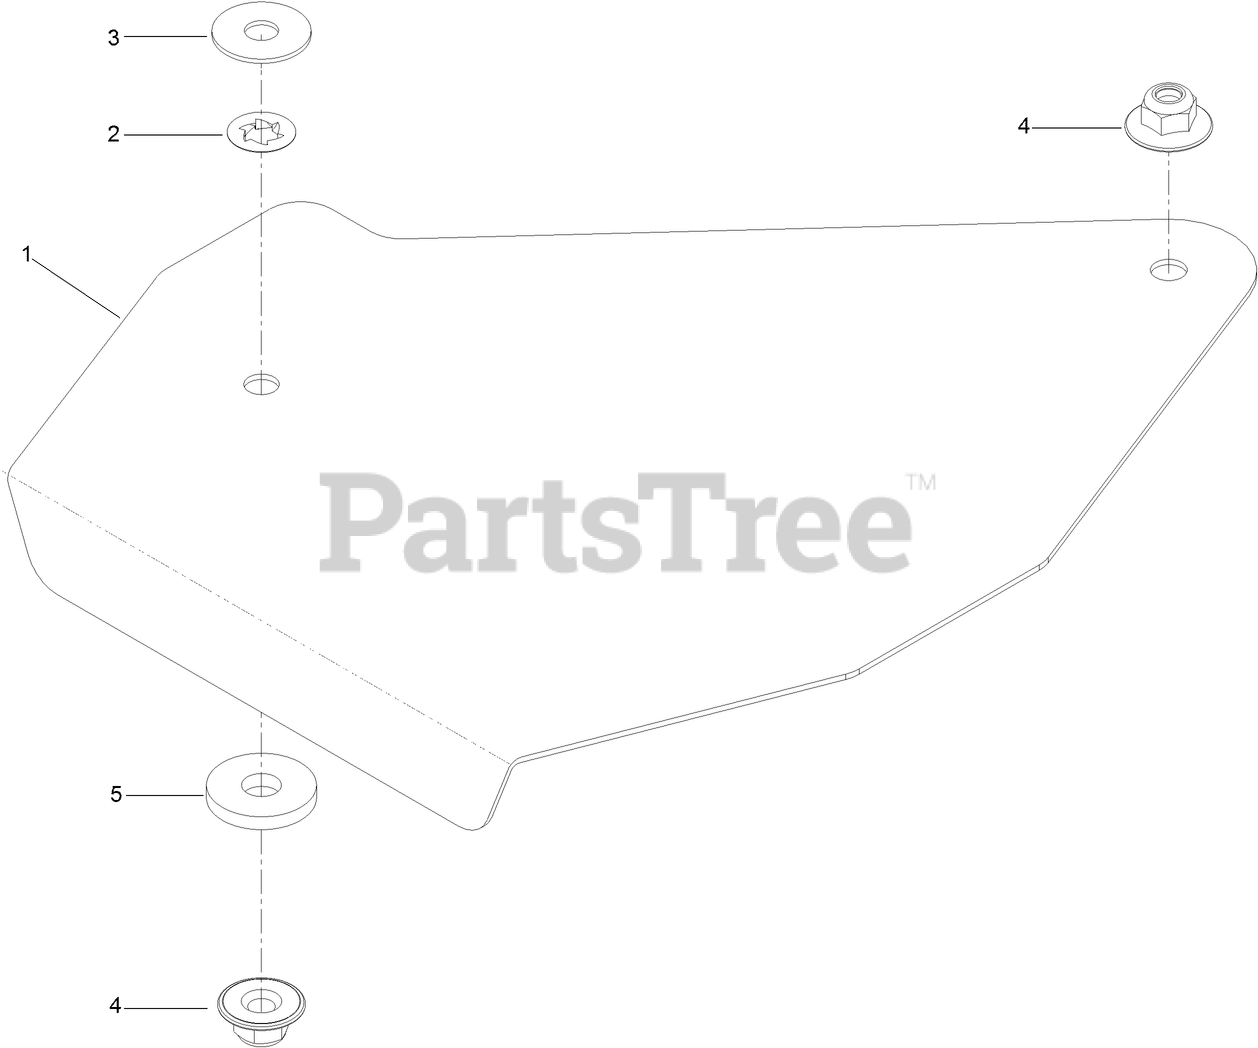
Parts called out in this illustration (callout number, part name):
1	PLATE-GUARD
2	NUT-PUSH
3	WASHER
4	NUT-FLANGE, NI
5	WASHER
